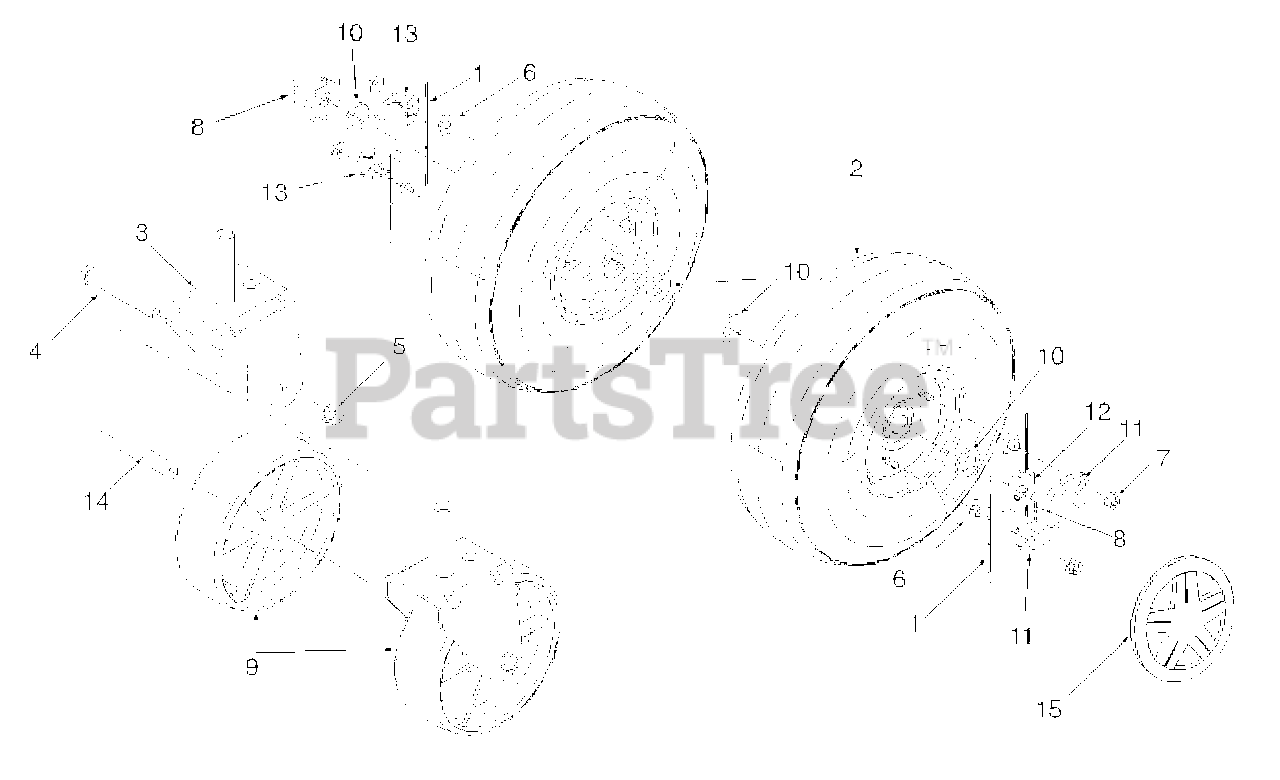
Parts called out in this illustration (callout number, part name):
1	Spring, Plastic Ratchet
2	Wheel Assembly, Complete
2	Ratchet Rim Ass'y, Complete
2	Tire, Pneumatic, 10 x 4
2	Valve, Tubeless Air
2	Bearing, Flange, .632 ID
3	Bracket Assembly, Pivot Wheel
4	Screw, Hex Cap, 3/8-16 x 3.0
5	Nut, Hex Flange Lock, 3/8-16
6	Nut, Special Hex 1/4-20
7	Nut, Hex Flange Lock, 1/4-20
8	Pin, Internal Cotter
9	Wheel, 6.00 x 2.00
10	Washer, Flat, .64 x 1.12 x .12
11	Pawl, LH .345 ID
12	Ratchet, Wheel, .5 Serr ID x 1.62
13	Pawl, RH .345 ID
14	Spacer, .384 ID x .5 OD x 2.3 Lg
15	Hubcap, 4.0 Gray
